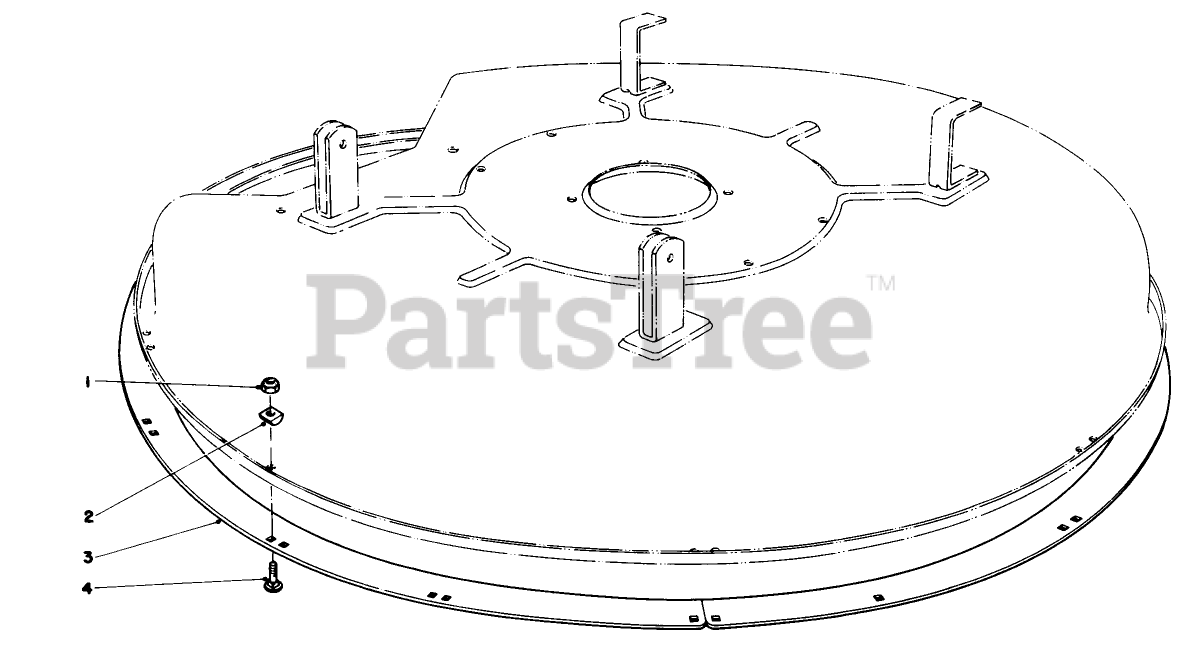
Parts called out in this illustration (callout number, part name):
1	NUT-LOCK, NI
3	DECK RING *B
4	BOLT-CARR
